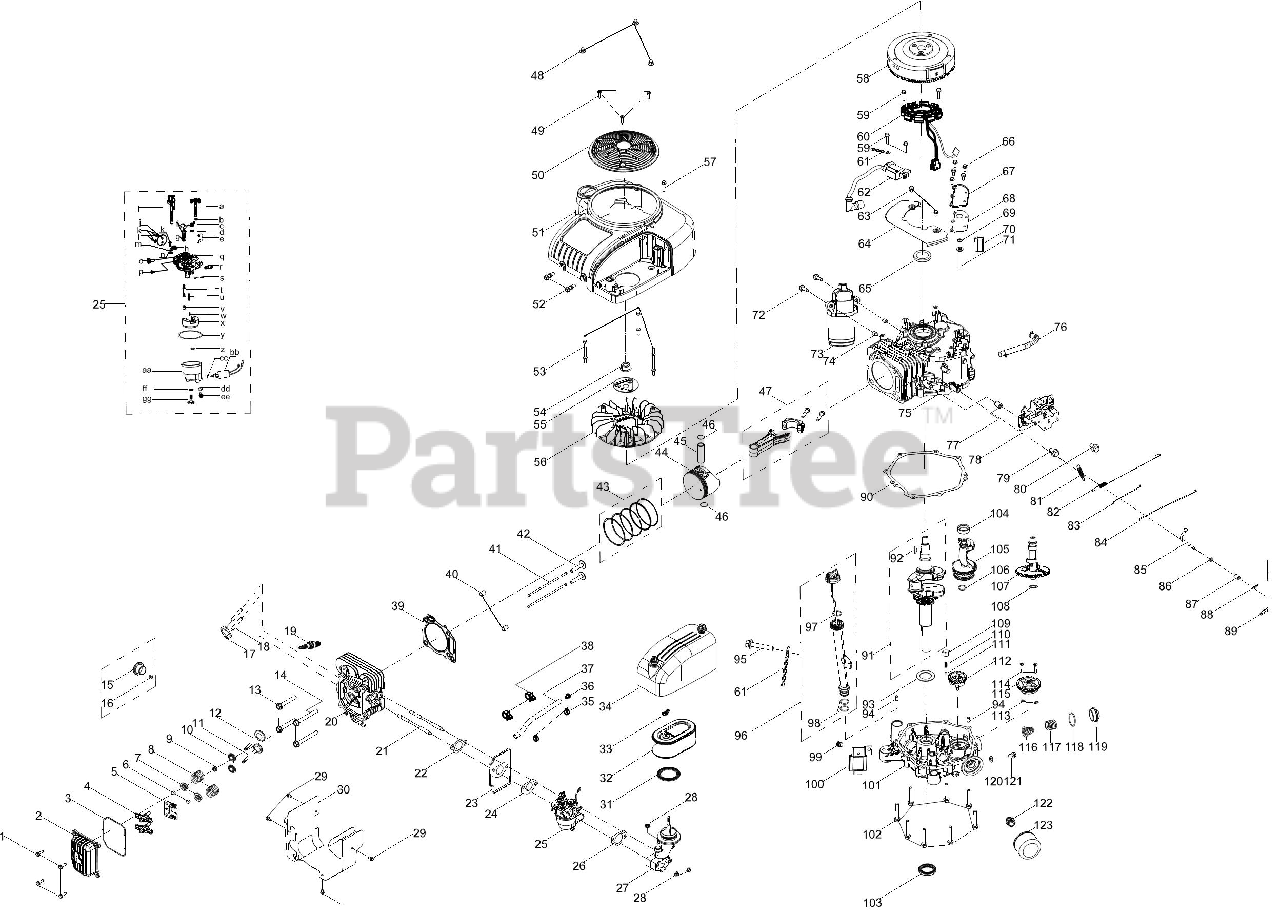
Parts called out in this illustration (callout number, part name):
1	Bolt, M6x22
2	Valve Cover
3	Gasket, Valve Cover
4	Rocker Arm Assembly
5	Rocker Arm Base
6	Valve Adjust Cap, Exhaust
7	Valve Spring Seat
8	Valve Spring
9	Intake Valve Seal
10	Valve Spring Seat
11	Exhaust Valve
12	Intake Vavle
13	Bolt, M10x1.25x65
14	Bolt, M10x1.25x85
15	Spark Arrester
16	Self-tappling Screw, ST5x8
17	Gasket, Muffler
18	Stud, M8x47
19	Spark Plug
20	Cylinder Head
21	Stud, M6-8x140
22	Gasket, Carburetor Insulator
24	Gasket, Carburetor
25	Carburetor
26	Gasket, Intake Manifold
27	Intake Manifold
29	Bolt, M5x10
31	Ring,Air Filter
32	Air Filter Assembly
32	Genuine Factory Parts AIR FILTER
33	Butterfly Nut
34	Air Filter Cover
35	Clamp
37	Fuel Hose, 6.3x12.5x290
38	Clip
39	Gasket, Cylinder Head
40	Pin, 12x16
41	Push Rod
42	Tappet
43	Piston Ring Set
45	Piston Pin
46	Circlip
47	Connecting Rod Assembly
48	Nut,M6
49	Self-tappling Screw, ST5.5x25
53	Stud, M6x99
54	Nut, M16x1.5
55	Cooling Fan Plate
56	Cooling Fan
57	Bolt, M6x16
59	Bolt, M6x28
60	Charging Coil
61	FLEXIBLE CLAMP
62	Ignition Module
63	Bolt, M6x10
65	Oil Seal, 35x52x7
66	Bolt, M6x14
67	Breather Cover
68	Gasket, Breather Cover
69	Breather Valve
70	Breather Filter Screen
71	Second Air Valve Seat
72	Bolt, M8x40
73	Electric Starter
74	Pin, 10x14
76	Breather Hose
77	Bush, 6.5x15x20
78	Governor Gear Bracket Assembly
79	Bolt, M6x38
80	Bolt, M6x18
81	Governor Spring
82	Idle Spring
83	Choke Lever
84	Throttle Linkage
85	Governor Gear Shaft
86	Washer, 6x1x12
87	GOVERNOR SEAL
88	Cotter Pin
89	Governor Lever
90	Gasket, Crankcase
91	Crankshaft
92	Woodruff Key
93	Washer, 35.4x2x54
95	Bolt, M6x35
97	O-Ring, 21.9x2.62
98	O-Ring, 21.2x2.8
99	ENGINE PLUG 3/8 NPT
101	Crankcase Cover
102	Bolt, M8x54
103	Oil Seal, 35x52x7
104	Bearing, 6202
105	Balance Shaft
106	Washer, 15.4x1x25
108	Washer, 16.4x1x24
111	Ball S6.35
112	Governor Gear
113	O-Ring, 10x2.65
116	Breather Filter Screen
117	Breather Spring
118	O-Ring, 35.5x2.65
119	Breather Cover
120	Washer, 8.3x1.5x17
121	Bolt, M8x15
122	Connection Pipe
123	Oil Filter
123	Cub Cadet OIL FILTER
123	Genuine Factory Parts OIL FILTER
